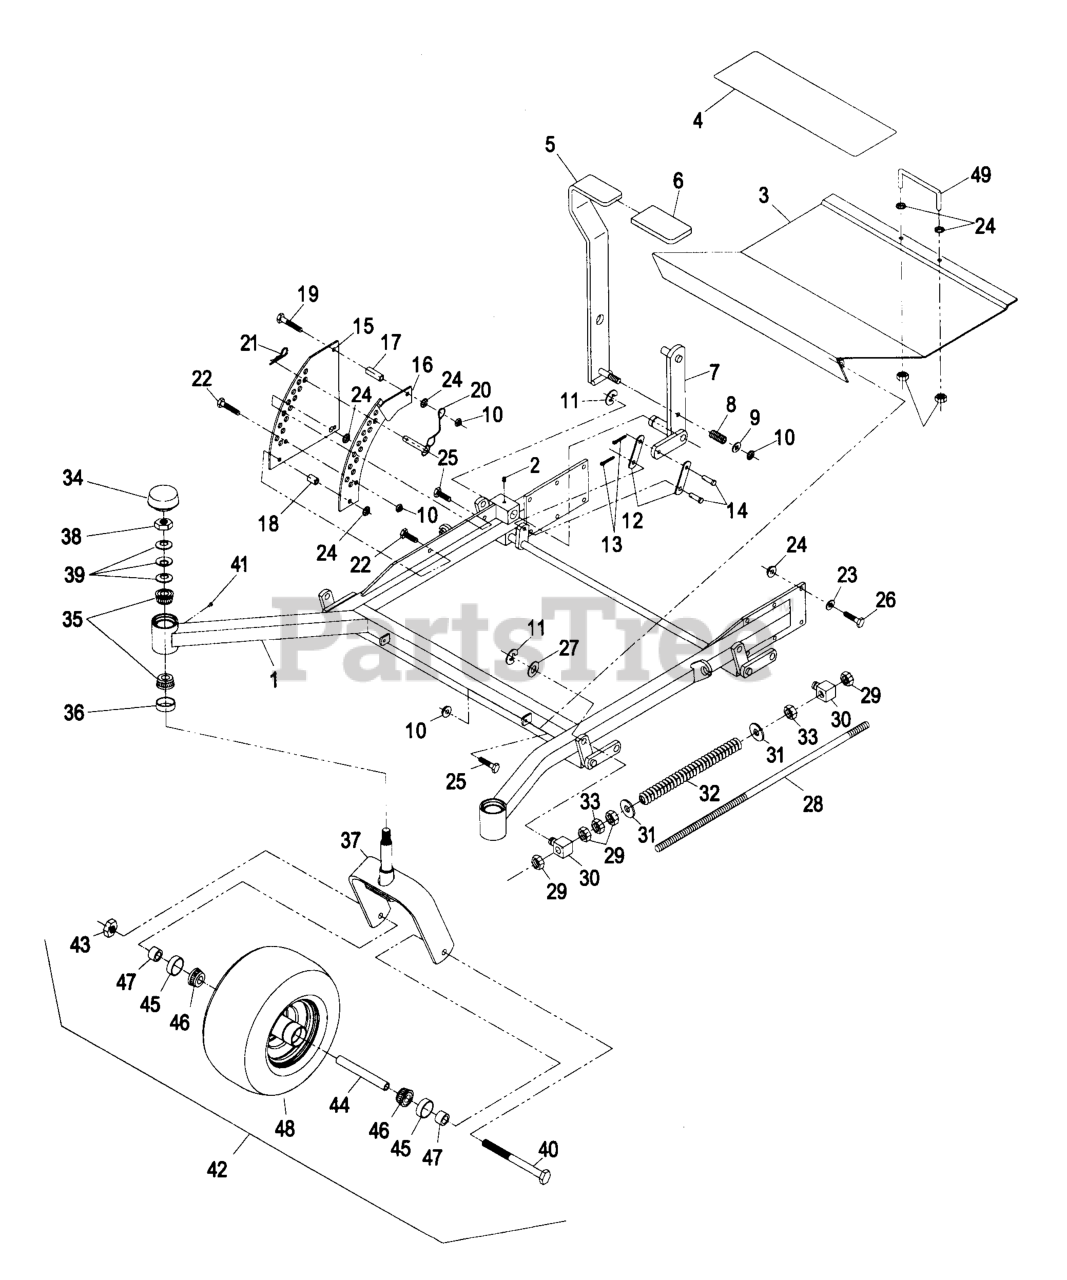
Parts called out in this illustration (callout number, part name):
4	PAD-ANTISKID
6	GRIP-LEVER, LIFT
8	SPRING-COMPRESSION
12	ARM-LIFT, DECK
14	PIN-CLEVIS
15	PLATE-LIFT, DECK
16	PLATE-LIFT, DECK
17	BUSHING-LEVER, LIFT
18	BUSHING-LEVER, LIFT
20	PIN-HITCH (W/LANYARD)
21	PIN-COTTER
28	ROD-LIFT, DECK
30	SWIVEL-DECK MOUNT, REAR
32	SPRING-SUPPORT, DECK
34	CAP-GREASE
35	Cone-Bearing Tapered Roller
36	SEAL-GREASE
39	WASHER-BELLVILLE
42	CASTER WHEEL ASM
44	SPACER-CASTER, FRONT
45	SEAL-BEARING
46	BEARING-CONE, TAPERED ROLLER
47	SPACER-BEARING
48	WHEEL AND TIRE ASM
49	HANDLE,DECK
